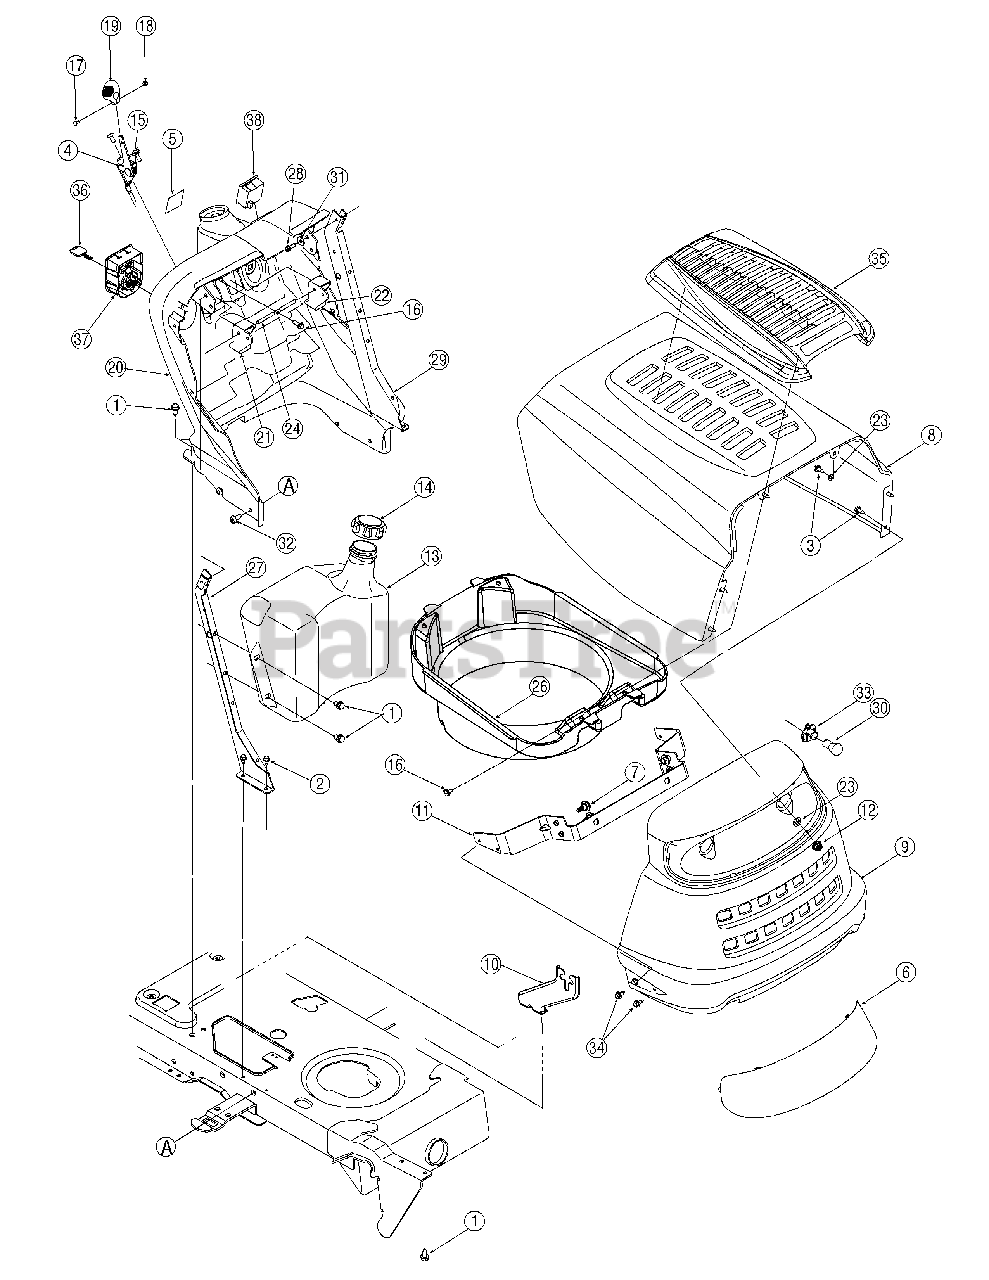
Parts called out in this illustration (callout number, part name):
1	Screw, 5/16-12 x.750
2	Self-tapping Screw, 1/4-20 x.5
3	Hex Cap Screw, 1/4-20 x.62
4	Throttle Control/Cable
5	Choke Plug
6	Headlight Lens
7	Shoulder Screw,.43 x.29
13	Fuel Tank, Two Gallon
14	Fuel Cap
15	Screw, 1/4-14 x.625
16	Self-tapping Screw, 1/4-15 x.75
17	Truss Phillips Screw, #8-32 x.375
18	Hex Nut, #8-32
19	Throttle Control Knob
20	Dash Panel
21	Cruise Control Button
22	Parking Brake Button
23	Flat Washer, .265 x .938 x 1.20
24	Brake/Cruise Pivot Rod
26	Hood Plenum
30	Lamp
31	Bell Washer,.265 x.75 x.062
32	Screw, 5/16-18 x.75
33	Headlight Socket
34	Hex Index Screw, 1/4-20 x .625
35	Hood Cover, 5 Style
36	Ignition Key w/ plastic cover
36	Ignition Key w/o plastic cover
37	Ignition Switch
38	Systems Ind. Monitor w/ Hour Meter (if equipped)
38	Systems Ind. Monitor w/Ammeter
